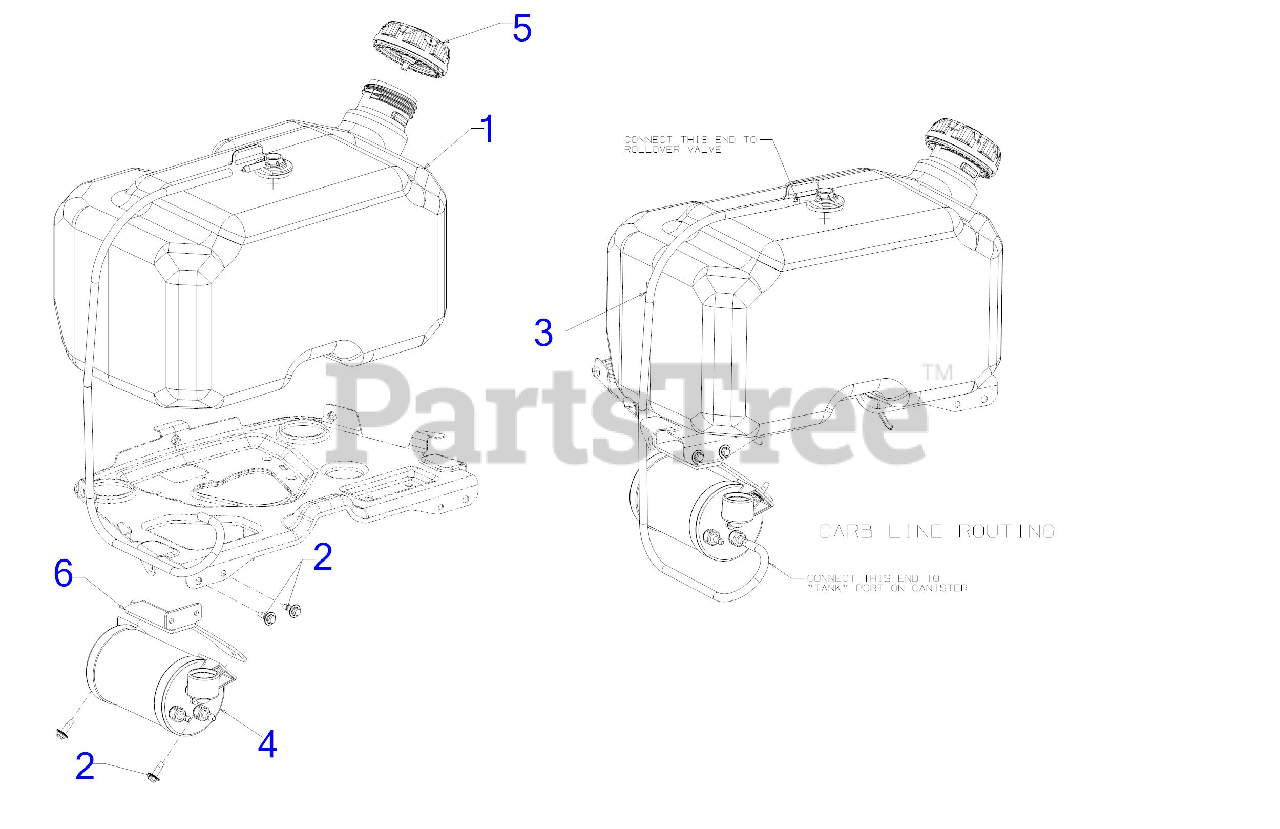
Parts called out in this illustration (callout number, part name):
1	FUEL TANK ASSEMBLY
2	SCREW M6-1 x .625
3	VENT HOSE 3/16 ID
4	CARBON CANISTER
5	FUEL CAP W/TETHER
